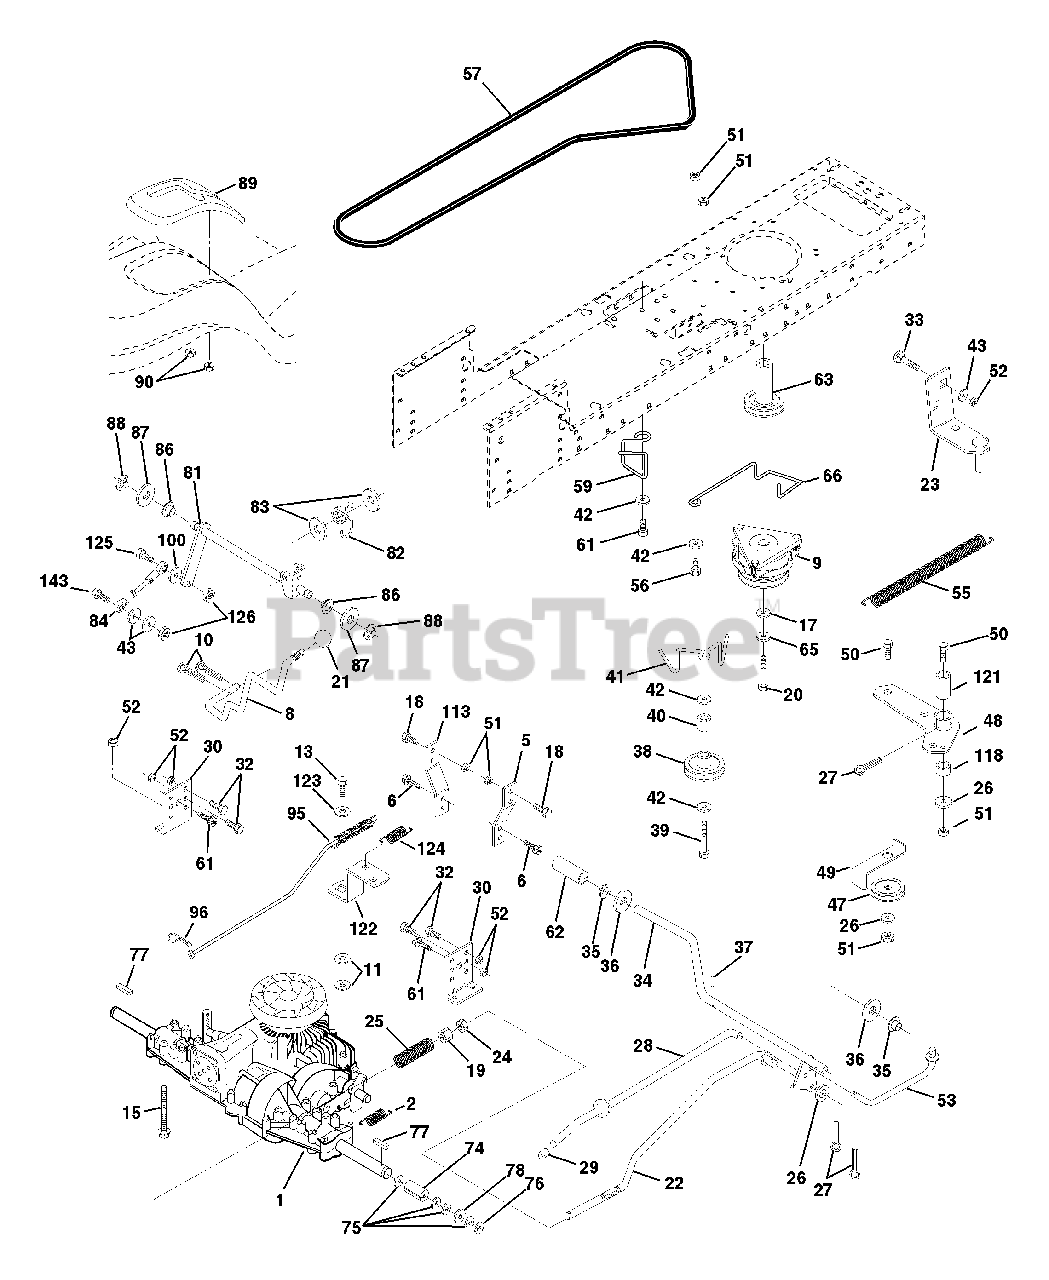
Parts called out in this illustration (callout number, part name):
1	Transaxle Peerless
2	Spring, Return Brake
5	Strap Torque
6	Screw Thdrol 5/16-18 x 3/4
8	Rod Shift Hydro LT
9	Clutch Elect
10	Pin Cotter 1/8 x 1 CAD
13	Bolt 1/4-28 Unf Gr. 8 W/Patch
15	Bolt Hex Flghd 5/16-18 Gr. 5
17	Washer 1-1/2 OD x 15/32 ID x .250
18	Bolt Fin Hex 3/8-16 Unc x 1 Gr. 5
19	Nut Lock Hex W/Wsh 3/8-16 Unc
20	Bolt Hex 7/16-20 x 4-1/4 5 Ga. 1.38
22	Rod, Brake
23	Bracket Asm Mtg. Cl
24	Nut, Hex Jam 3/8-16 Unc
25	Spring, Brake Rod
26	Washer
27	Pin Cotter 1/8 x 3/4 CAD.
28	Rod, Parking Brake
29	Cap, Parking Brake
30	Bracket, Transaxle
32	Bolt Hex Hd 5/16-18 Unc x 3/4
33	Bolt Rd Hd Sqnk 5/16-18 Unc x 3/4
34	Shaft, Foot Pedal
35	Bearing, Nylon
37	Pin, Roll
38	Pulley, Idler, Flat
40	Spacer, Split
41	Keeper, Belt, Idler
42	Washer 13/32 x 13/16 x 12 Gauge
43	Washer 11/32 x 5/8 x 12 Ga.
47	Pulley, Idler, V-Groove
48	Bellcrank Assembly
49	Retainer, Belt
50	Bolt
51	Nut Crownlock 3/8-16 UNC
52	Nut, Crownlock 5/16-18 Unc
53	Link, Clutch
55	Spring, Return, Clutch
56	Bolt Hex 3/8-16 x 1-1/4
57	V-Belt, Ground Drive
59	Keeper, Center Span
61	Screw Thdrol. 3/8-16 x 3/4 Ty. TT
62	Cover, Pedal
63	Pulley, Engine
65	Washer
66	Keeper Belt Engine
74	Spacer, Axle PVST
75	Washer 25/32 x 1-1/4 x 16 Gauge
77	Key, Square
78	Washer 25/32 x 1-5/8 x 16 Gauge
81	Shaft Asm. Cross Hydro
82	Spring Torsion T/A
83	Washer 17/32 x 3/4 x 16 Ga.
84	Rod, Tie PVST 20"
86	Bushing Rod Strig. 629/632 ID
87	Washer 21/32 x 1-1/4 x 16 Ga.
88	Ring Klip #5304-62
89	Console, Shift
90	Nut Self-Thd Wsh-Hd 1/4 Zinc
95	Rod Asm Bypass PVST
96	Retainer Spring 1" Zinc/Cad
100	Washer 11/32 x 3/4 x 16 Ga.
113	Strap Torque LH LT
118	Spacer Bellcrank
121	Nyliner Clutching STL
122	Plate Bypass PVST
123	Washer 9/32 x 5/8 x 16 Ga.
124	Spring Return PVST
125	Bolt Fin Hex 5/16-18 Unc x 1
126	Nut Lock 5/16-18 Unc
